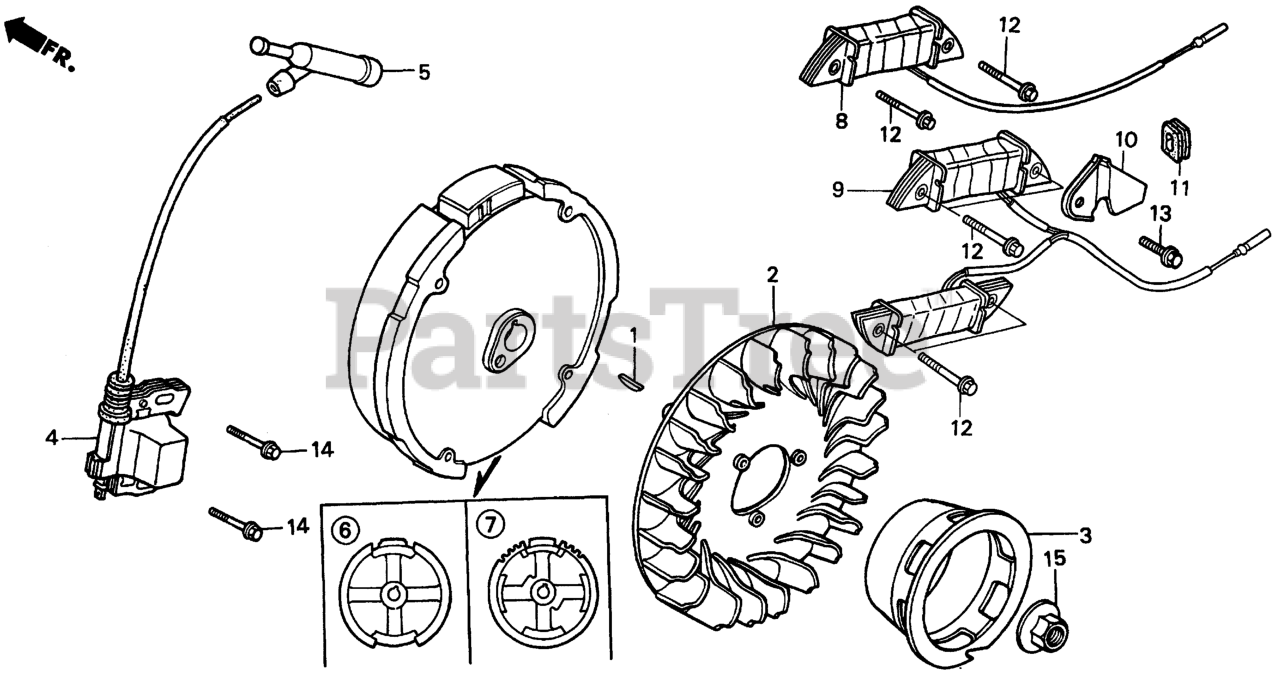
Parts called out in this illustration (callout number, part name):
1	KEY, SPECIAL WOODRUFF (25X18)
2	FAN, COOLING
3	PULLEY, STARTER
4	COIL ASSY., IGNITION Use up to Engine SN 1530314.
5	CAP ASSY., NOISE SUPPRESSOR (Honda Code 3526837). (NICHIWA Y-EZ RTFM256)
7	FLYWHEEL (STARTER MOTOR)
8	COIL ASSY., LAMP (12V/25W)
11	GROMMET, WIRE
12	BOLT, FLANGE (6X28) (CT200) Use up to Engine SN 1530314.
14	BOLT, FLANGE (6X25) Use up to Engine SN 2056819.
15	NUT, SPECIAL (14MM)
